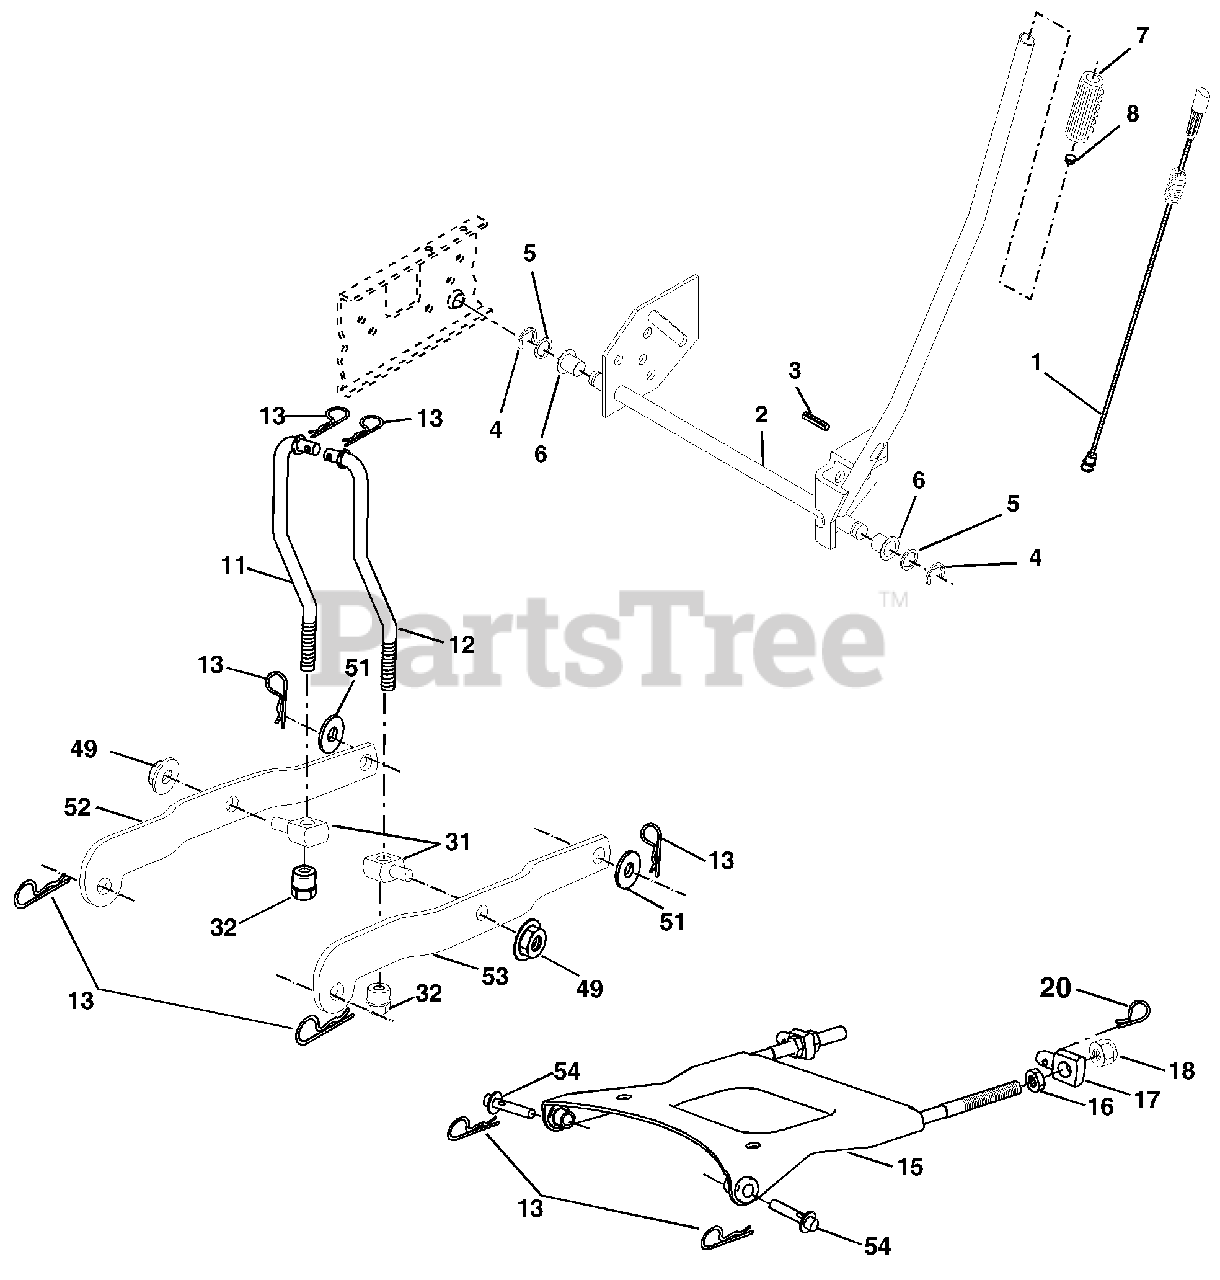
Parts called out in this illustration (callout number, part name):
1	Wire Asm Inner W/plunger 17 32
2	Shaft Asm Lift LH Inf Hgt P/L
3	Pin Groove 1 500 Zinc
4	E Ring #5133-62
5	Washer 21/32 x 1 x 21 Ga.
6	Bearing Nylon Blk 629 Id
7	Grip Handle
8	Button Plunger
11	Link Lift LH
12	Link Lift RH
13	Retainer Spring
15	Plate Asm Suspension Front
16	Nut Jam Hex 1/2-13 unc
17	Trunnion Blk Zinc
18	Nut Lock W/wsh 1/2-13 unc
20	Retainer Spring
31	Trunnion Suspension Arm
32	Nut Lift Link 7/16-20
49	Nut Hex Flange Lock
51	Washer 17/32 x 7/8 x 16 Ga.
52	Arm Suspension Rear LH
53	Arm Suspension Rear RH
54	Pin Flange
